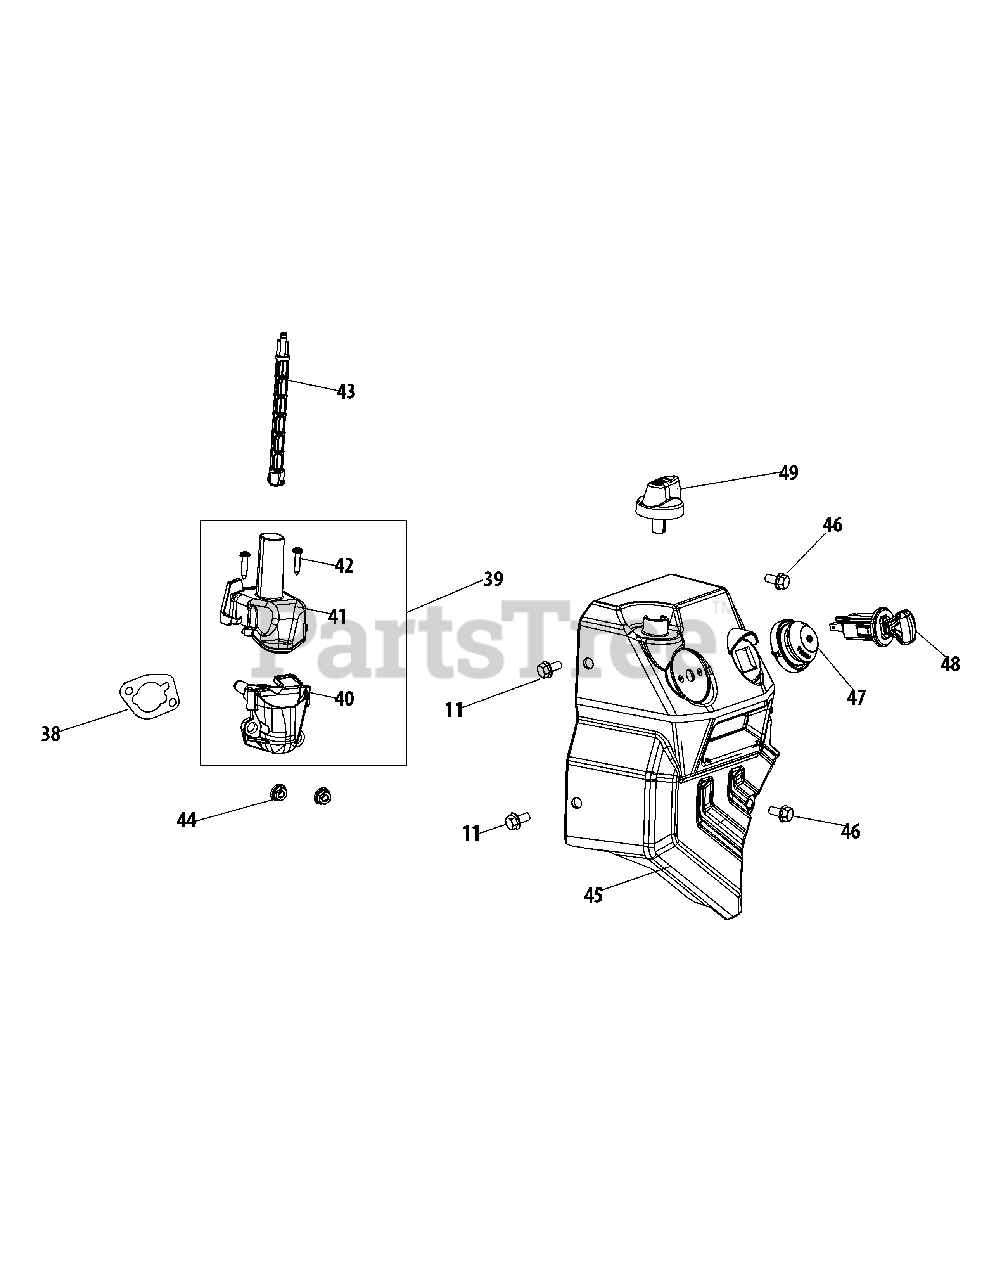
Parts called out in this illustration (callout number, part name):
11	Bolt, M6×12
38	Gasket, Air Filter
39	Heater Box
40	Air Filter Base
41	Upper Cover, Heater Box
42	Self-tappling Screw, ST4.2×16
43	Choke Linkage
44	Nut, M6
45	Control Panel
46	Bolt, M6×18
48	Stop Switch
48	Stop Switch Key
49	Choke Lever
